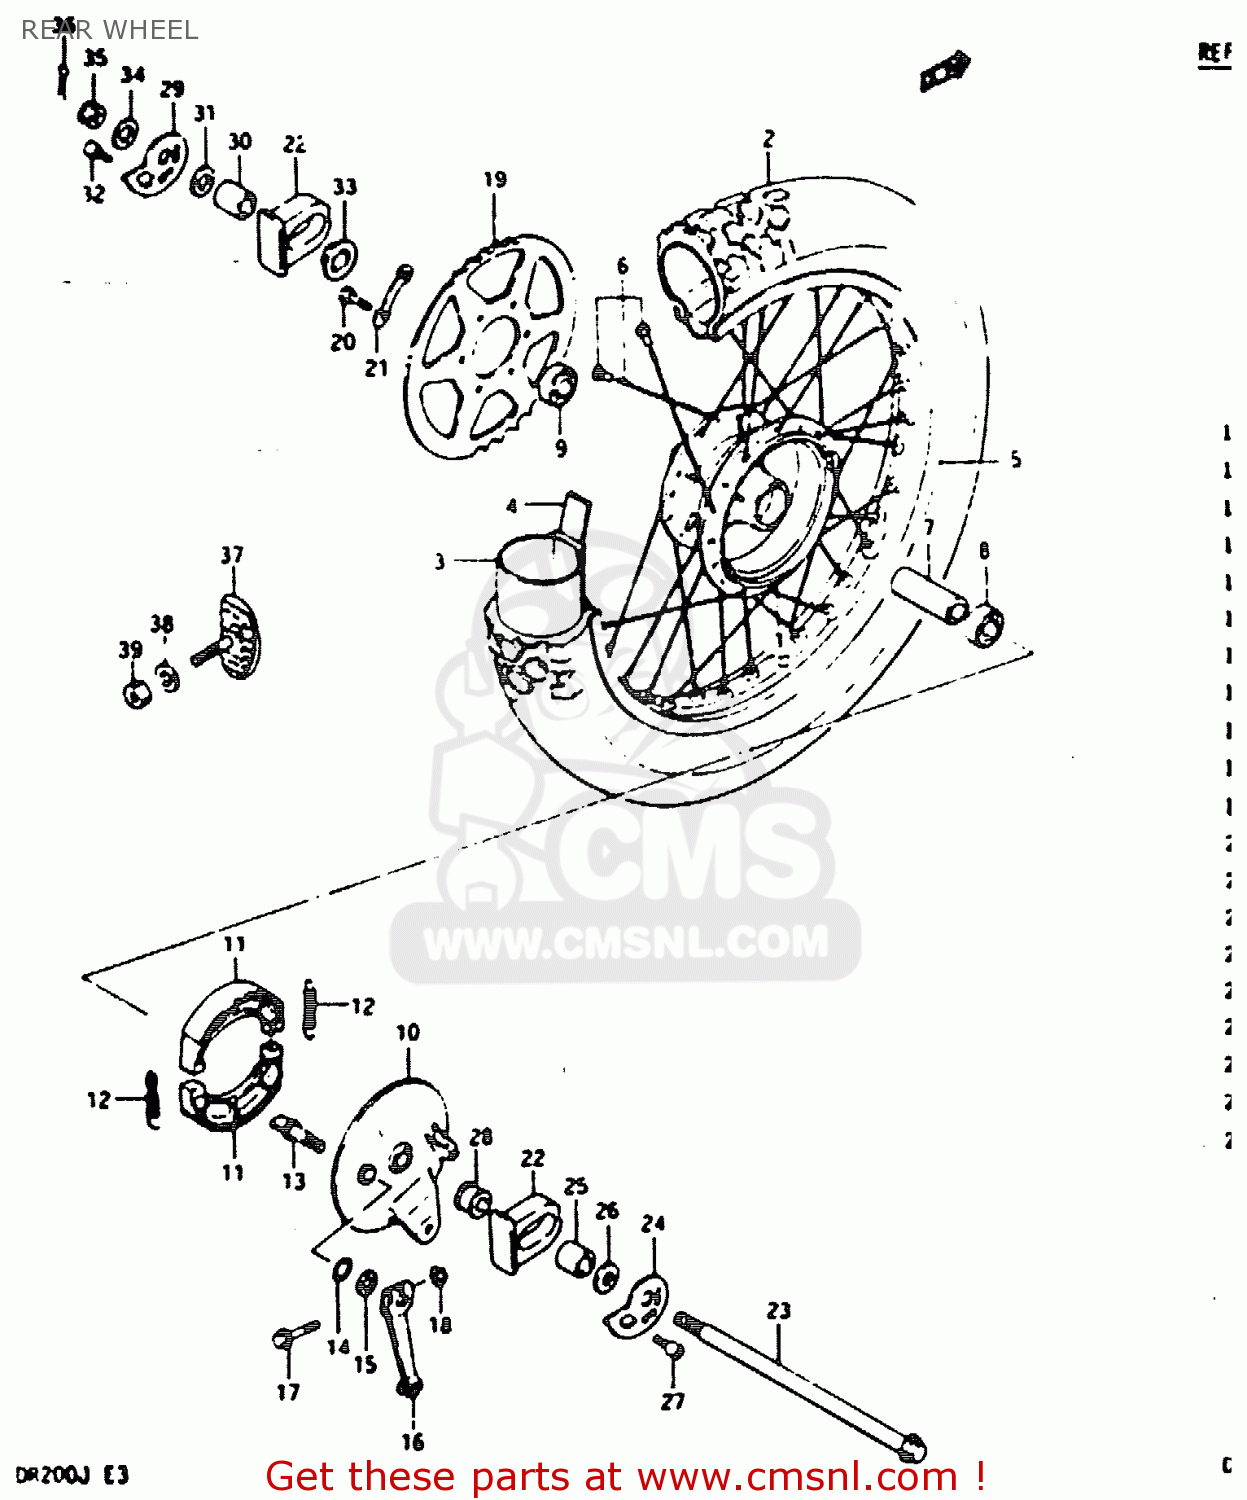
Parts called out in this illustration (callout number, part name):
1	HUB,REAR
2	TIRE,REAR 100/100-18
3	TUBE ASSEMBLY,WHEEL,INNER
4	PROTECTOR,WHEEL,INNER
5	RIM,REAR WHEEL
6	SPOKE SET,RR WHEEL
7	SPACER(15.3X21.7X107.5)
8	BEARING
9	BEARING
10	PANEL,RR BRAKE ANCHOR
11	SHOE,BRAKE
12	SPRING(L:34)
13	CAM,FRONT BRAKE
14	O-RING (D:2.4 ID:13.8)
15	WASHER (14.5X22X1.6)
16	LEVER,RR BRAKE CAM
17	BOLT
18	NUT
19	SPROCKET,REAR
20	BOLT(8X30)
21	WASHER
22	CAP,RR SWINGING ARM
23	AXLE,REAR
24	ADJUSTER,CHAIN,R
25	SPACER,CHAIN ADJUSTER
26	WASHER(15.5X30X3.2)
27	BOLT,CHAIN ADJUSTER
28	SPACER,RR AXLE,R
29	ADJUSTER,CHAIN,L
30	SPACER,CHAIN ADJUSTER
31	WASHER(15.5X30X3.2)
32	BOLT,CHAIN ADJUSTER
33	SPACER,RR AXLE,L
34	WASHER
35	NUT 14MM
36	COTTER PIN
37	STOPPER,BEAD
38	WASHER
39	NUT
